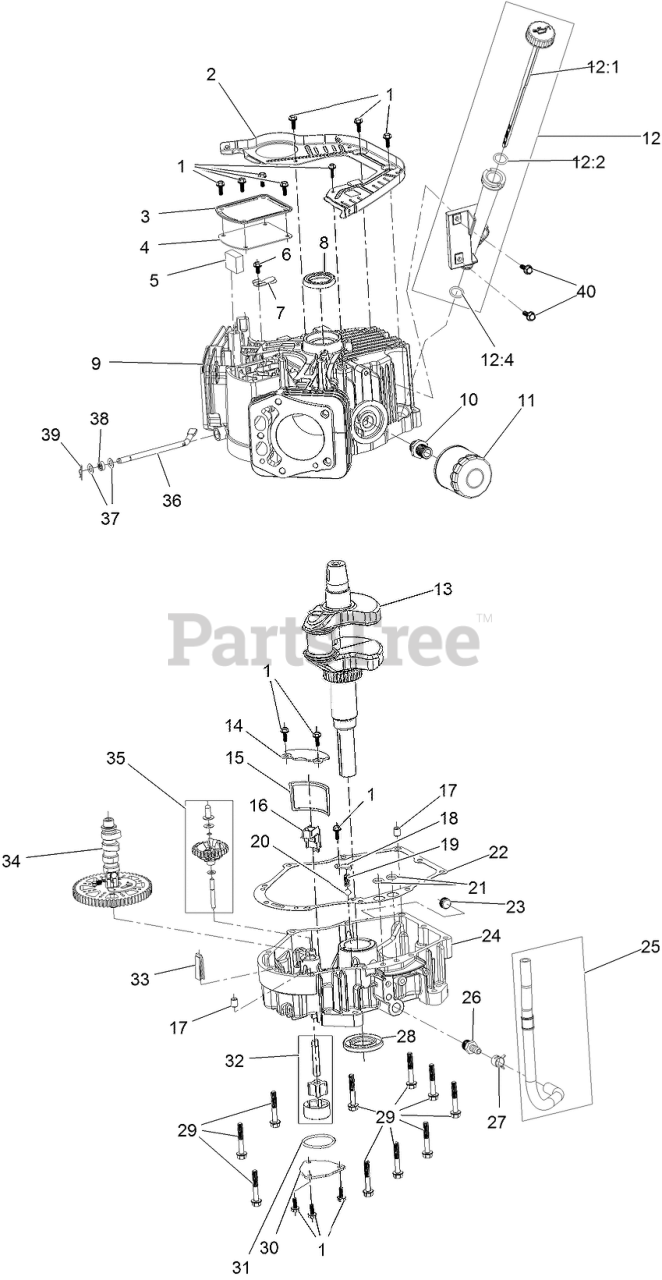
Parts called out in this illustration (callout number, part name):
1	SCREW-HHF
2	BAFFLE
3	COVER-BREATHER
4	GASKET-BREATHER
5	FILTER-BREATHER
6	SCREW-HHF
7	VALVE-BREATHER
8	SEAL-OIL
9	CRANKCASE
10	FITTING-THREADED, OIL FILTER
11	FILTER-OIL
12	OIL TUBE ASM
12:1	DIPSTICK
12:2	O-RING
12:4	O-RING
13	CRANKSHAFT
14	COVER-SCREEN, OIL
15	SCREEN-OIL
16	RETAINER-SCREEN
17	PIN-DOWEL
18	PLATE-RETAINER
19	SPRING
20	VALVE-BALL
21	O-RING
22	GASKET-COVER, CRANKCASE
23	PLUG-DRAIN
24	COVER-CRANKCASE
25	OIL DRAIN HOSE ASM
26	FITTING-HOSE
27	CLAMP-HOSE
29	SCREW-HHF
30	COVER-OIL PUMP
31	O-RING
32	OIL PUMP ASM
33	DEFLECTOR-OIL, RUBBER
34	CAMSHAFT
35	GOVERNOR ASM
36	ROD-GOVERNOR
37	WASHER-PLAIN
38	SEAL-OIL
39	PIN-HAIR
40	SCREW-HHF
